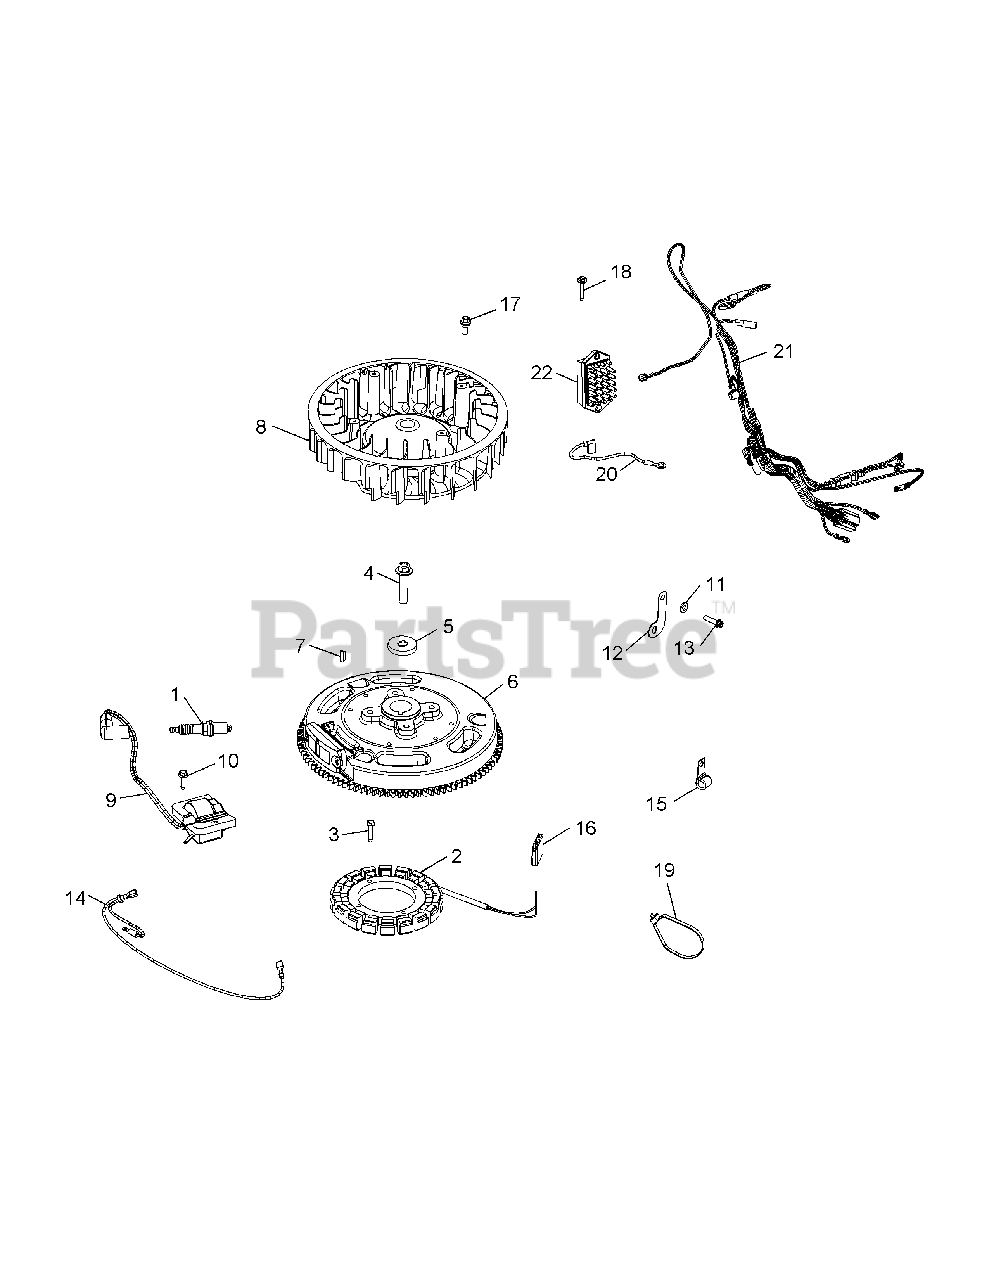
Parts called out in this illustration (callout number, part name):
2	15 Amp Stator Kit
3	Thread Forming Screw
4	Flange Screw, M10 x 1.5 x 45
5	Flat Washer, 13/32"
7	Key, 3/16 x 5/8
9	Ignition Module Kit
10	Thread Forming Screw
11	Flat Washer, 1/4
12	Ground Strap Bracket
13	Hi-Lo Hex Flange Screw
15	Cable Clip
17	Shoulder Bolt
18	Flange Screw, M4 x .7 x 25
21	Wiring Harness Assembly
22	Rectifier Regulator
